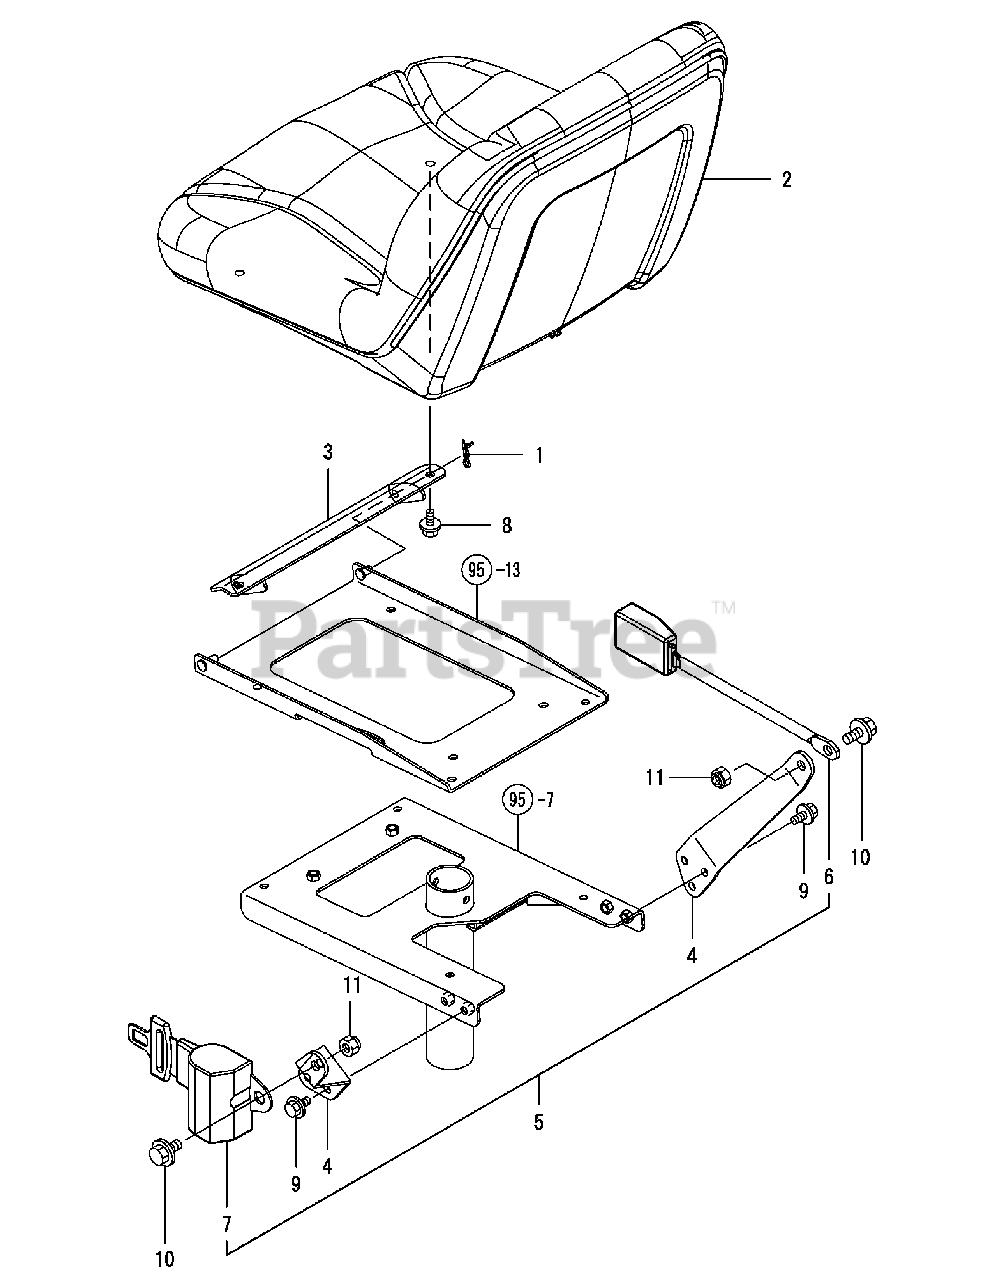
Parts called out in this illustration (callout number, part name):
1	PIN 8,COME-OFF SNAP
2	SEAT ASSY, OPERATOR
3	HINGE ASSY, SEAT
4	STAY, SEAT BELT
5	SEAT BELT ASSY
6	SEATBELT ASSY, L
7	BELT R,SAFETY CMP
8	BOLT M 8X 16 PLATED
9	BOLT M 8X 16 PLATED
10	BOLT M10X 20 PLATED
